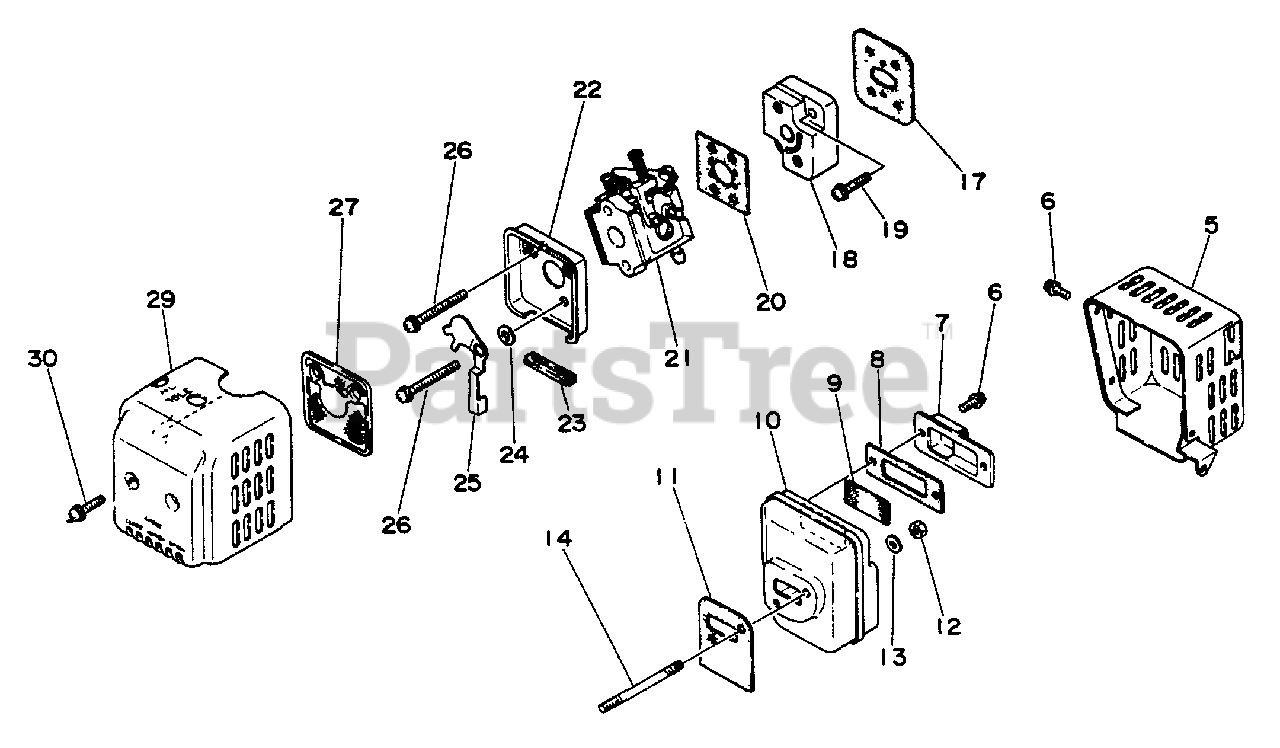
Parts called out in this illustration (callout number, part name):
5	COVER, EXHAUST
6	SCREW - 4X10
7	GUIDE, EXHAUST
8	GASKET, EXHAUST
9	SCREEN, SPARK ARRESTOR
10	MUFFLER
11	GASKET, EXHAUST
12	LOCKNUT - 5
13	WASHER - 5
17	GASKET, INTAKE
18	INSULATOR, INTAKE
19	SCREW - 5X20
20	GASKET, INTAKE
21	CARBURETOR WA-143
22	CASE, AIR FILTER
24	WASHER - 5
25	SHUTTER, CHOKE
26	SCREW - 5X40
27	FILTER, AIR
29	COVER, AIR FILTER
30	SCREW - 4X18
